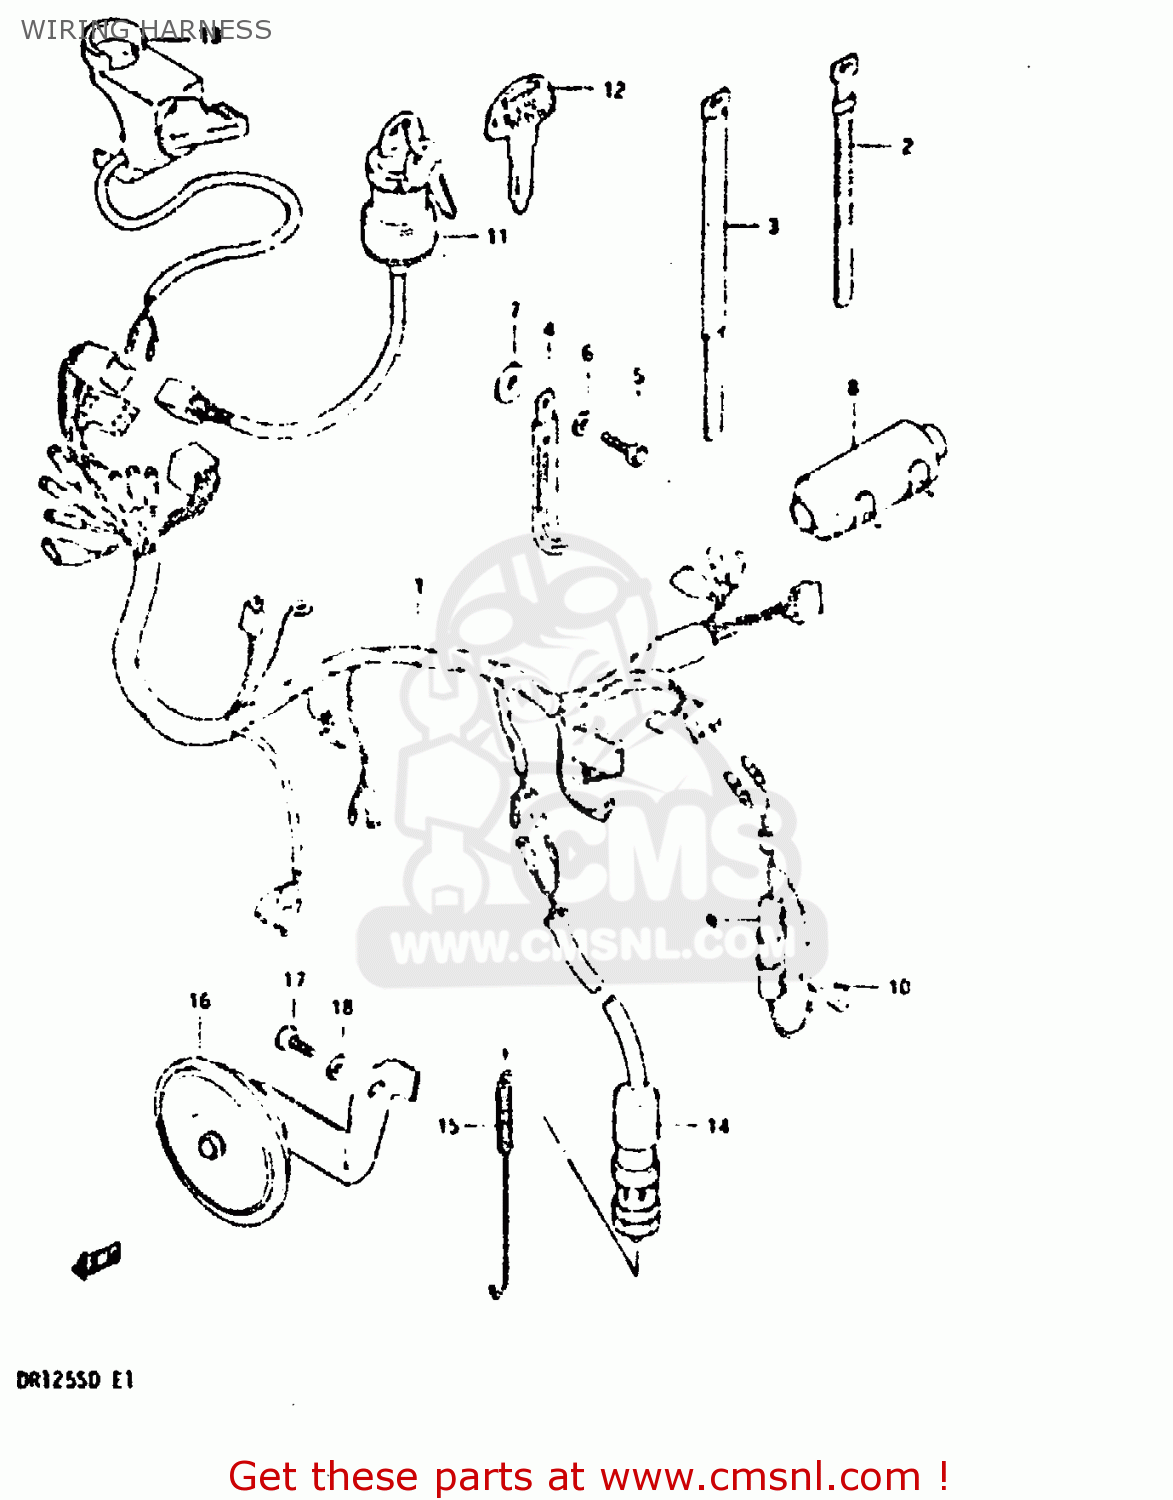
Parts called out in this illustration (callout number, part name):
1	WIRING HARNESS
2	CLAMP(L:120)
3	CLAMP
4	CLAMP
5	BOLT, UPPER
6	WASHER
7	WASHER
8	BOOT,WIRING HARNESS
9	BOX ASSEMBLY,FUSE
10	FUSE(15A)
11	SWITCH ASSEMBLY,IGNITION
12	KEY,BLANK
13	SWITCH ASSY,ENGINE STOP
14	SWITCH ASSEMBLY,STOP LAMP
15	SPRING
16	HORN ASSY
17	BOLT
18	WASHER
